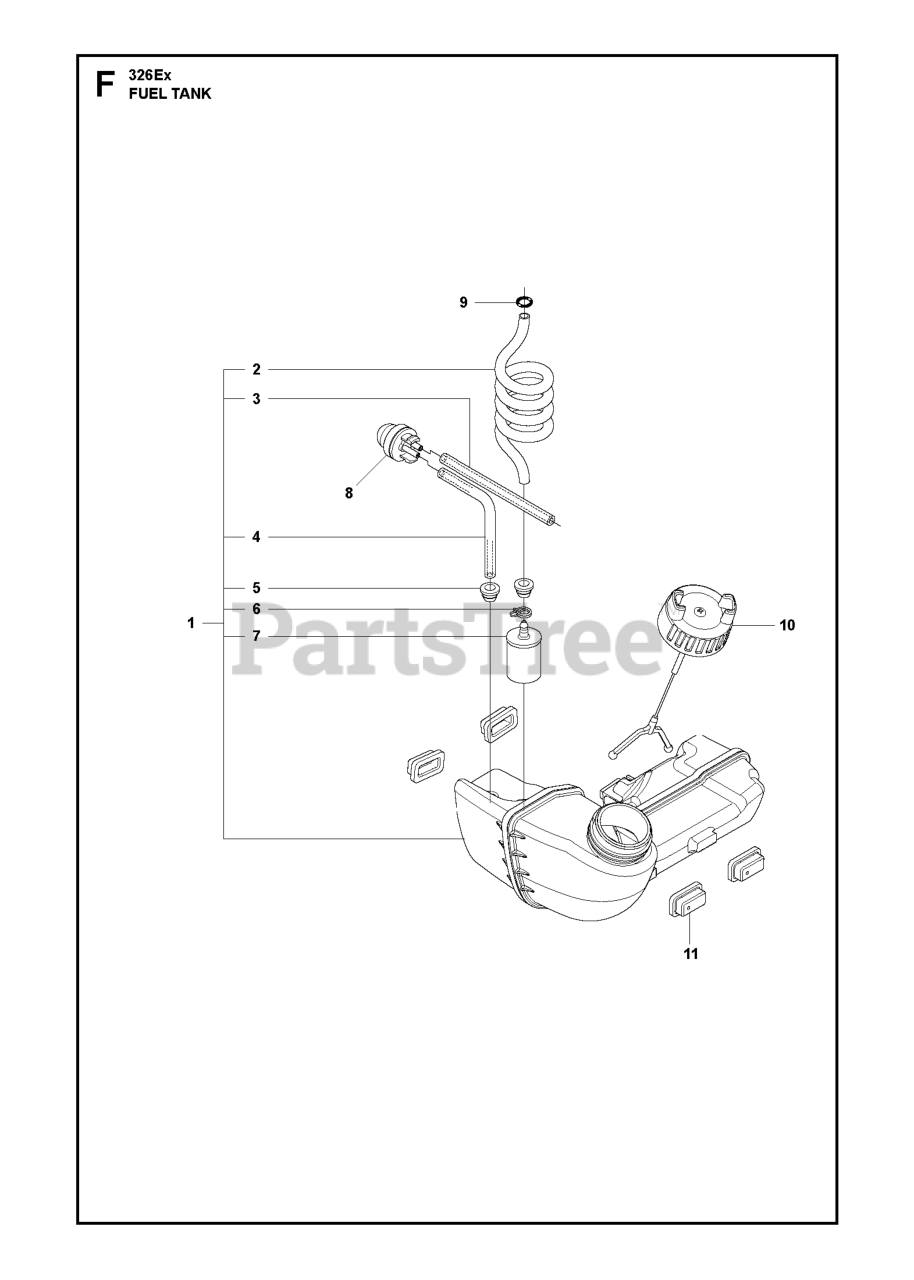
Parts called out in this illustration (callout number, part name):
1	RP FUEL TANK ASSY
2	FUEL HOSE
3	HOSE.FUEL L=102
4	HOSE.FUEL L=102
5	FUEL TANK BUSHING
6	HOSE CLAMP
7	RP FUEL FILTER
8	AIR PURGE BUBBLE
10	TANK CAP
